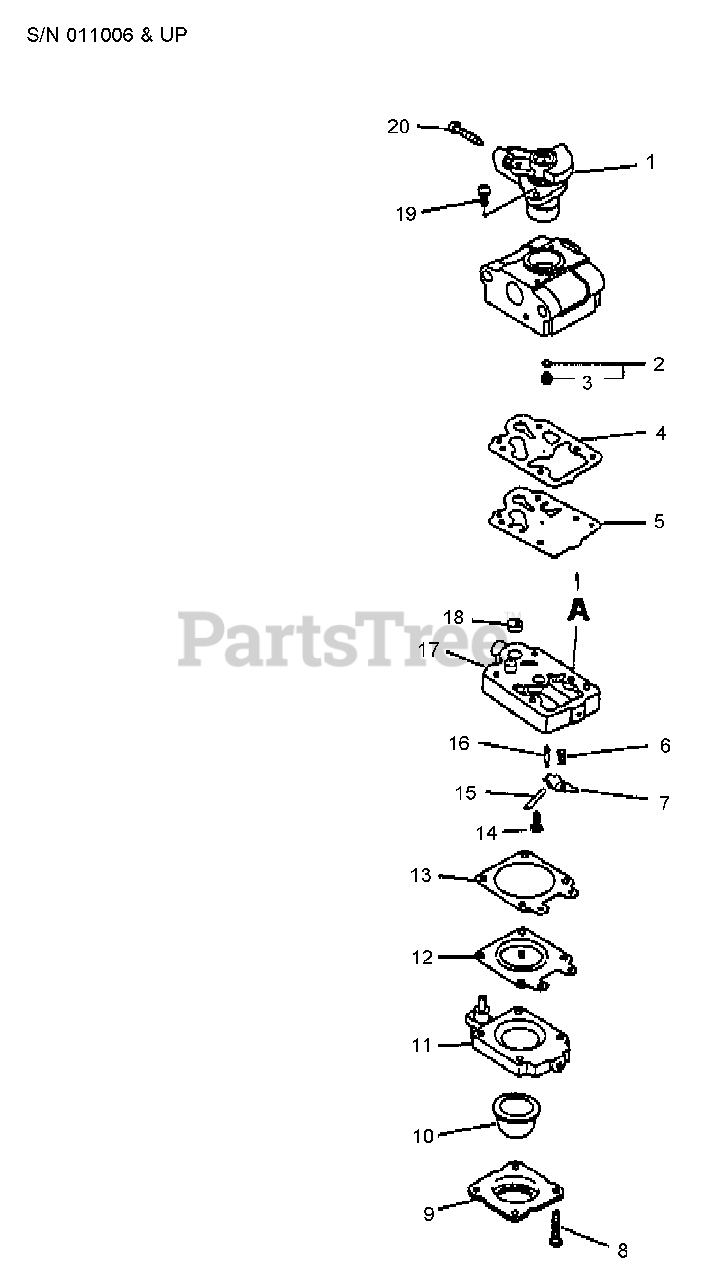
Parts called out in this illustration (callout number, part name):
1	VALVE, THROTTLE
2	JET KIT - 37
3	O-RING
4	GASKET, PUMP
5	DIAPHRAGM, PUMP
6	SPRING, METERING LEVER
7	LEVER, METERING
8	SCREW, PUMP COVER
9	RETAINER, PURGE BULB
10	BULB, PURGE
11	PURGE BASE ASSY
12	DIAPHRAGM, METERING
13	GASKET, METERING
14	SCREW, METERING LEVER PIN
15	PIN, METERING LEVER
16	VALVE, INLET NEEDLE
17	BASE, PURGE
18	STRAINER
20	SCREW, IDLE ADJUST
